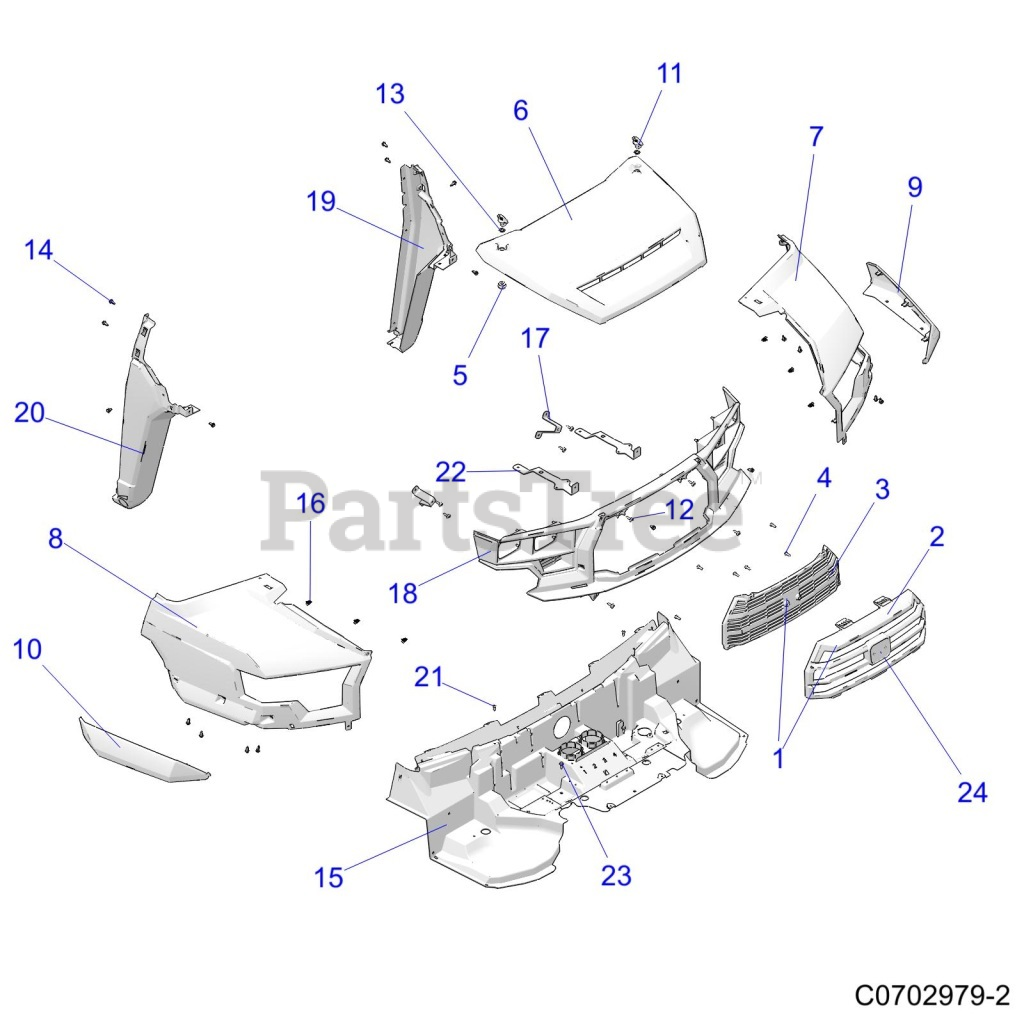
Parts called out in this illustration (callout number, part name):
1	ASM., GRILL, GRAVELY
2	GRILL, FRONT, UPPER, BLACK
3	GRILL, UPPER, TRIM
4	SCR-TXPH-#14 X .75 HI-LO RIE
5	GROMMET-LATCH
6	HOOD-ARNS,I.RED
7	FENDER-FRONT,ARNS,LH,I.RED
8	FENDER-FRONT,ARNS,RH,I.RED
9	FLARE-FENDER,ARNS,LH,BLK
10	FLARE-FENDER,ARNS,RH,BLK
11	LATCH, 1/4 TURN
12	SCR-TXTH-M6X1.0X25 RIE
14	RIVET-TUFLOK,.315-.325X.787 (5
15	LINER-HOOD,BLK
16	CLIP, DASH TRIM METAL
17	BRKT-FASCIA MOUNT
18	BEZEL-HEADLIGHT
19	COVER,FRONT,LH,BLK
20	COVER,FRONT,RH,BLK
21	SCR-TX TRUSS-#14X3/4,HI/LO ZBK
22	BRKT-MOUNT,RADIATOR,ARNS,BLK
23	SCR-M6X1.0X20,HXHD,FLG,TDFM,BL
